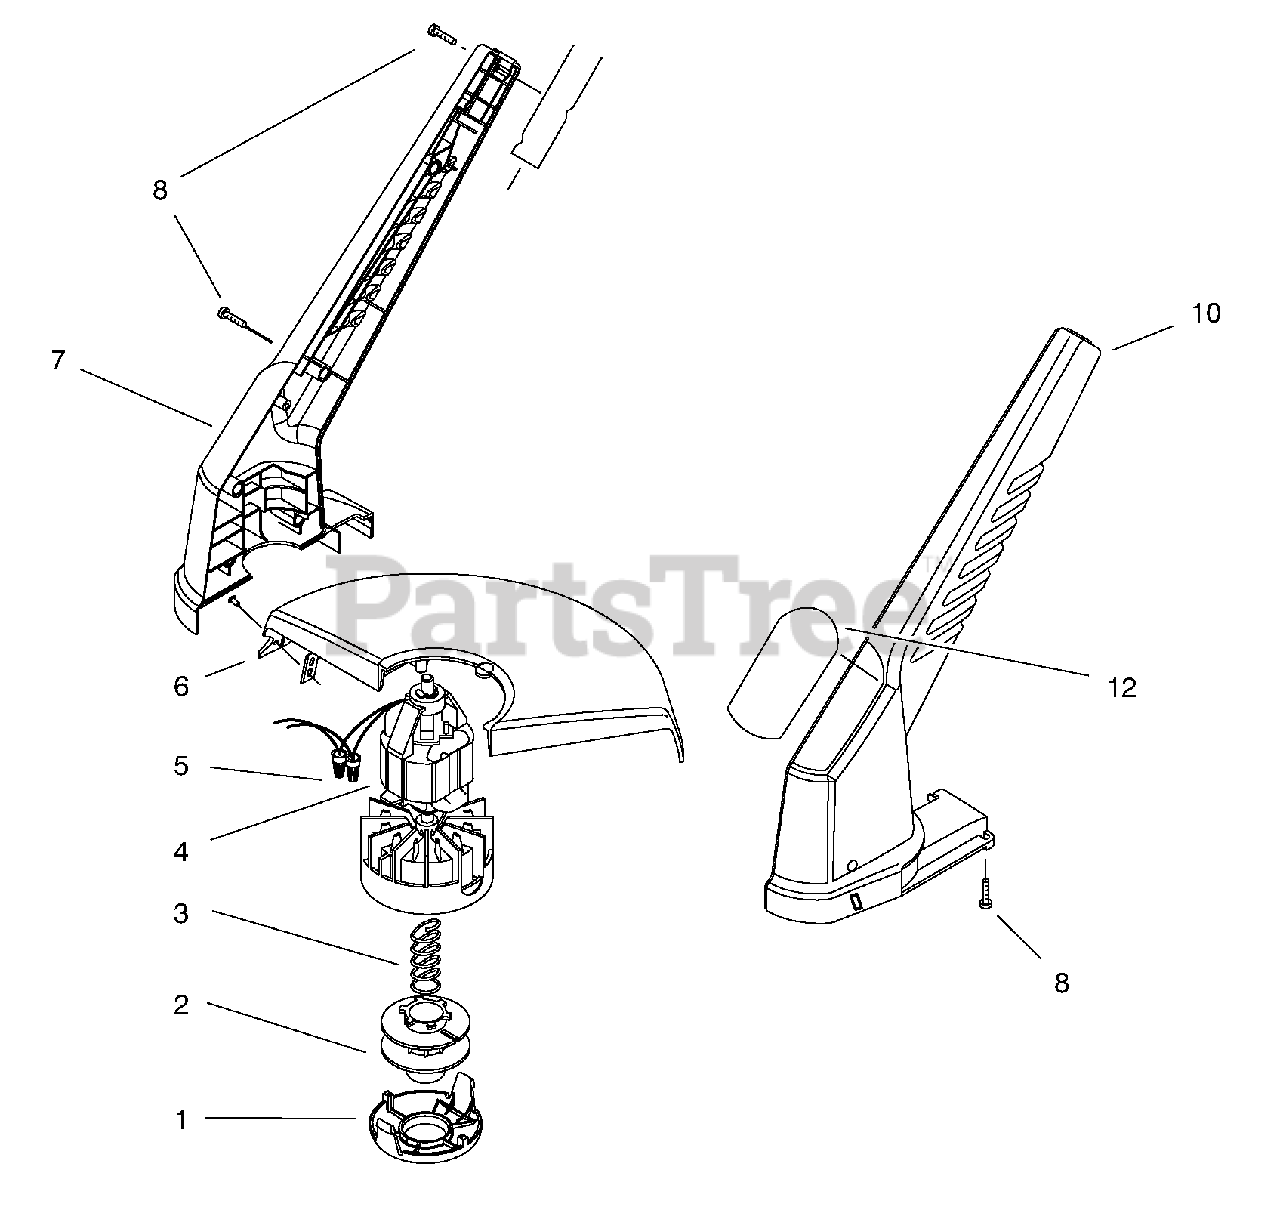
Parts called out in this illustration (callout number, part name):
4	Motor Assembly
5	Connector-Wire Nut
6	Shield Asm.
7	Housing R.H.
8	Screw-Pan Hd. Tapping
10	Housing L.H.
12	Decal-12" Trimmer
